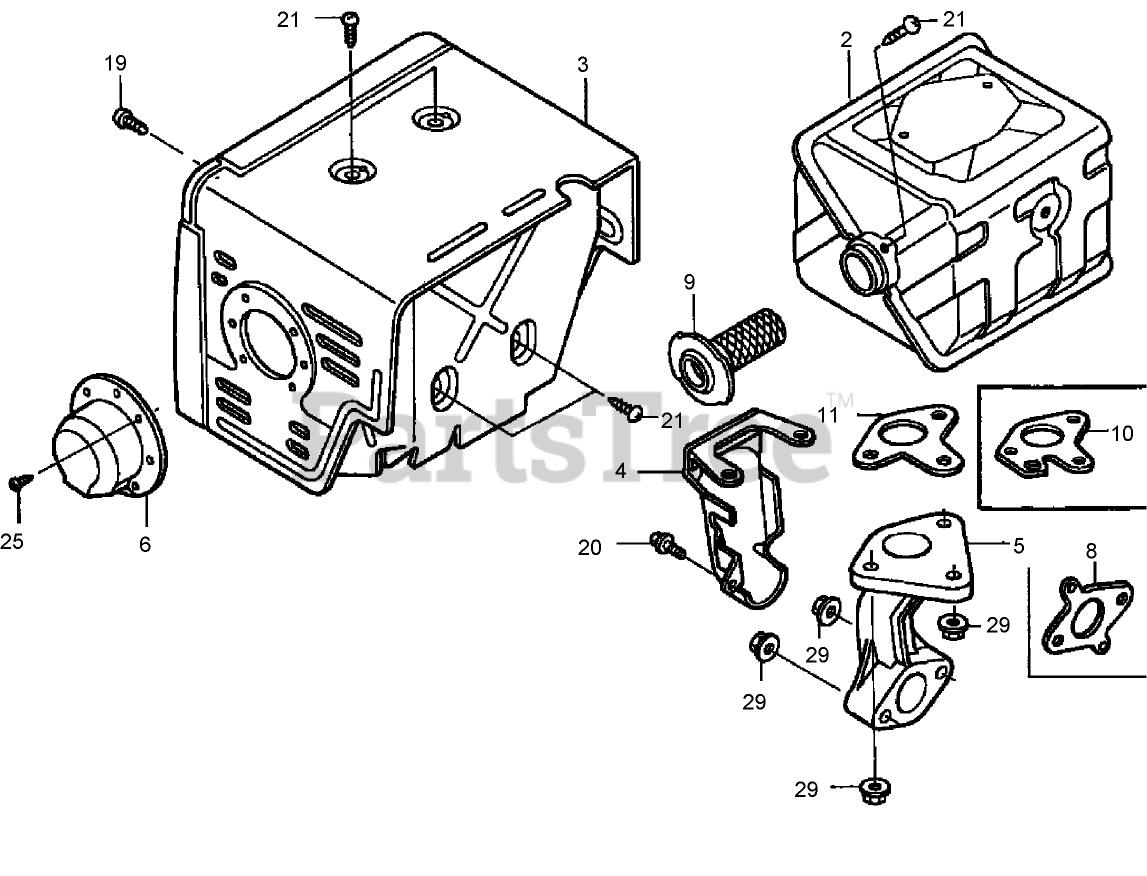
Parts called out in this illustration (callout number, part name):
2	MUFFLER (100DB)
3	PROTECTOR-MUFFLER
4	PROTECTOR-EXHAUST PIPE
5	PIPE-EXHAUST
6	CAP-MUFFLER
8	GASKET-EXHAUST PIPE
9	ARRESTER-SPARK
10	GASKET-MUFFLER (ARRESTER)
11	GASKET-MUFFLER
19	SCREW-TAPPING (6X10)
20	BOLT-FLANGE (6X12) (C T200)
21	SCREW-TAPPING (5X8)
25	SCREW-TAPPING (4X6)
29	NUT-FLANGE (8MM)
